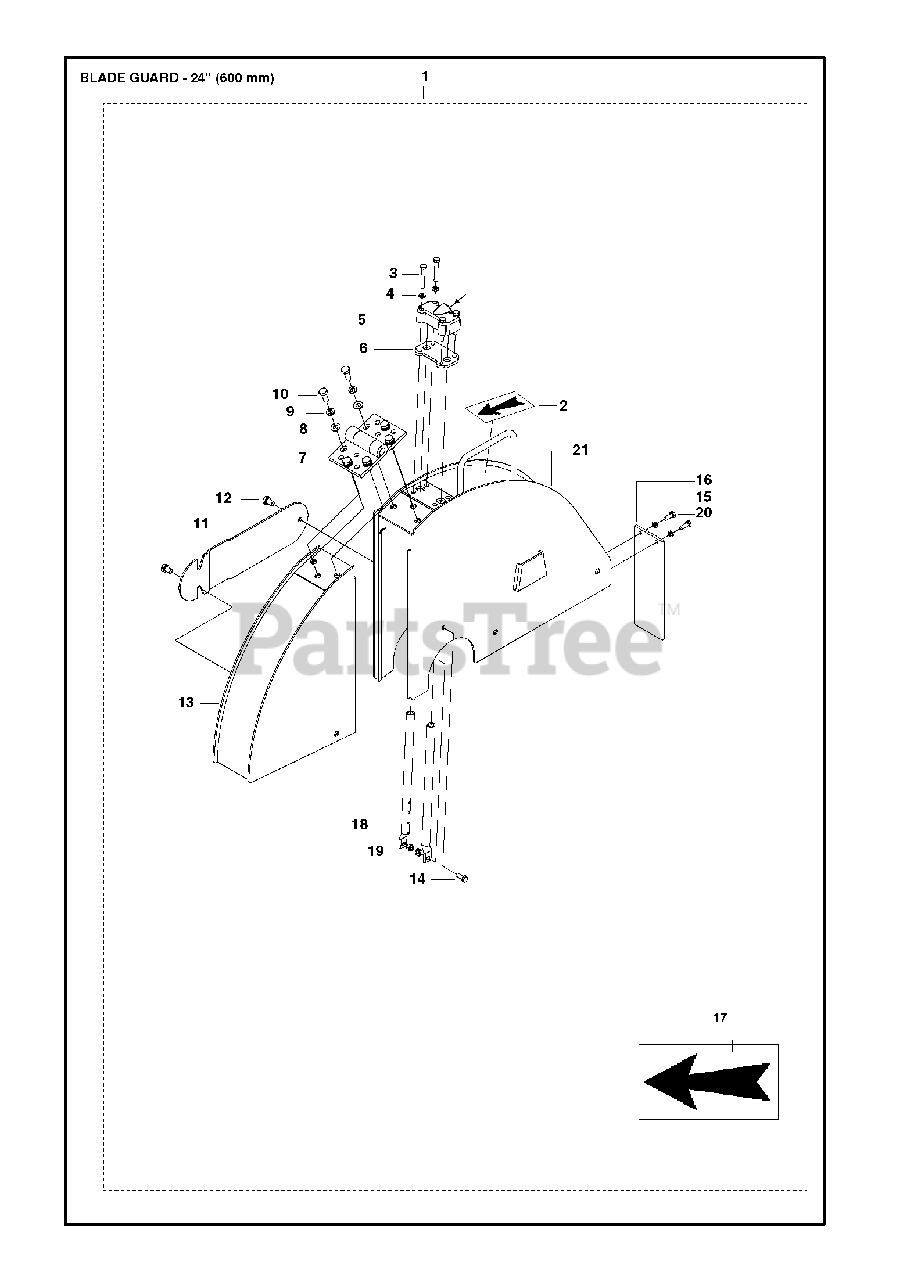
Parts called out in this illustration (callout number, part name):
8	WASHER
9	SPRING WASHER
19	HEXAGON LOCKING NUT
